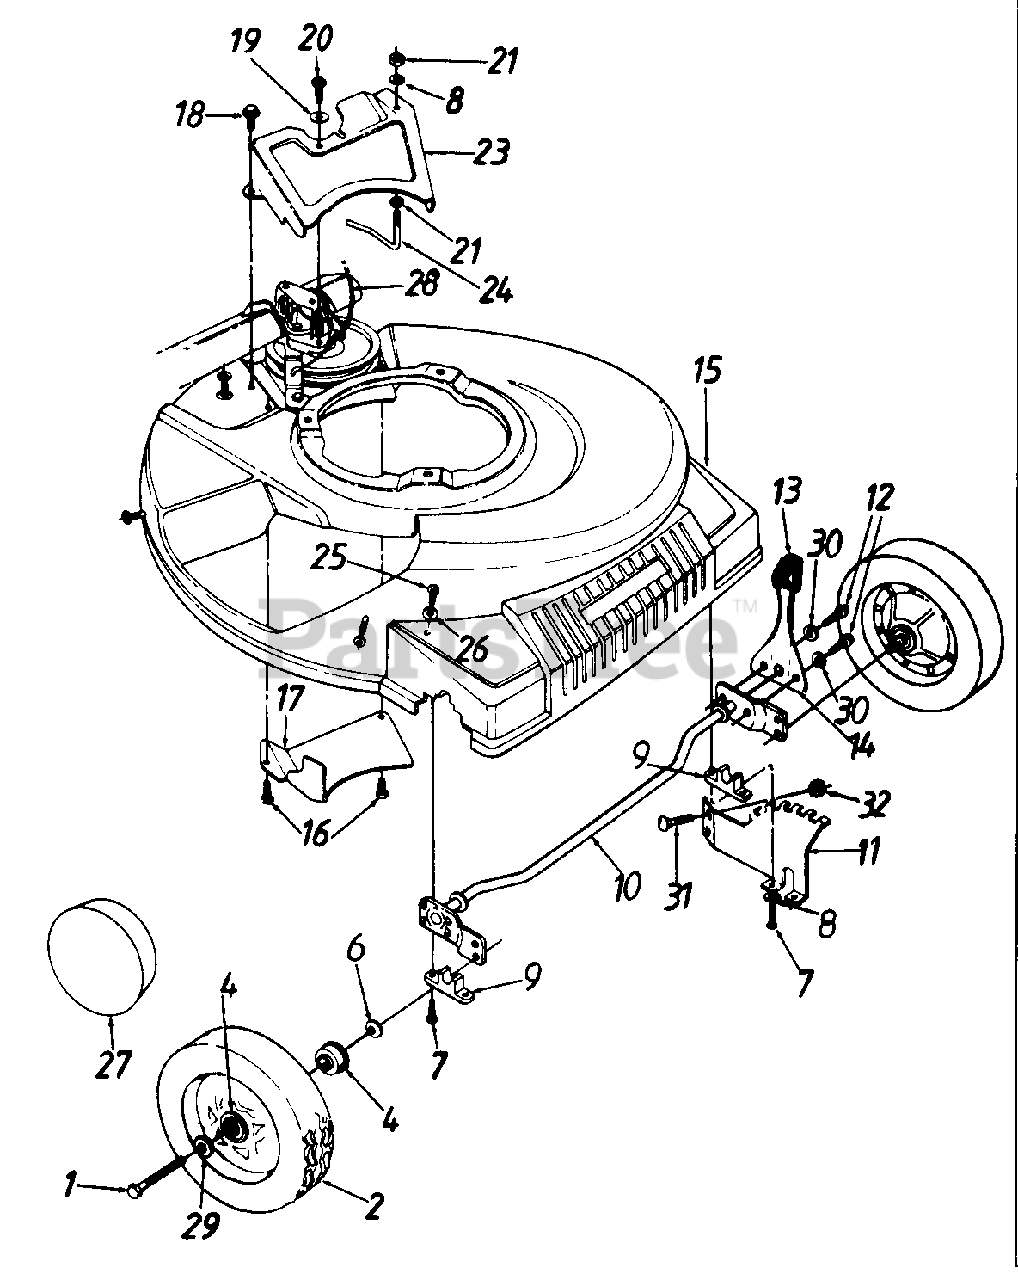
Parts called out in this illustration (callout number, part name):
1	Front Axle Bolt
2	Wheel Ass'y Comp.
4	Flange Ball Brg 501" I D
6	Bell-Wash .380" I. D x .88
7	Hex Wash. Hd. Scr 1/4-20 x 1" Lg.
8	L-Wash. 1/4" I D
9	Block Bushing
10	Axle Ass'y.
11	Height Adj. Bracket
12	Hex Wash. Hd TT-Tap Scr. 1/4-20 x 38" Lg
13	Knob
14	Spring Lever
15	Plastic Front End
16	Hex B-Tap Scr 1/4" x .38"
19	Bell-Wash .265" I.D. x.75"
20	Hex Wash. Hd. B-Tap Scr. 1/4 x .62" (Spec.)
21	Hex Nut 1/4-20 Thd.
25	Torx Truss Hd Scr 5/16 x .75"
26	Bell-Wash .345" I.D. x.88" O.D.
27	Hub Cap
28	S.P. Cable 50" Lg
29	Wave Wash .51" I D. x 75" O.D.
30	External L-Wash 1/4" I.D
31	Carr. Bolt 1/4-20 x 5" Lg
32	Hex L-Nut 1/4-20 Thd.
